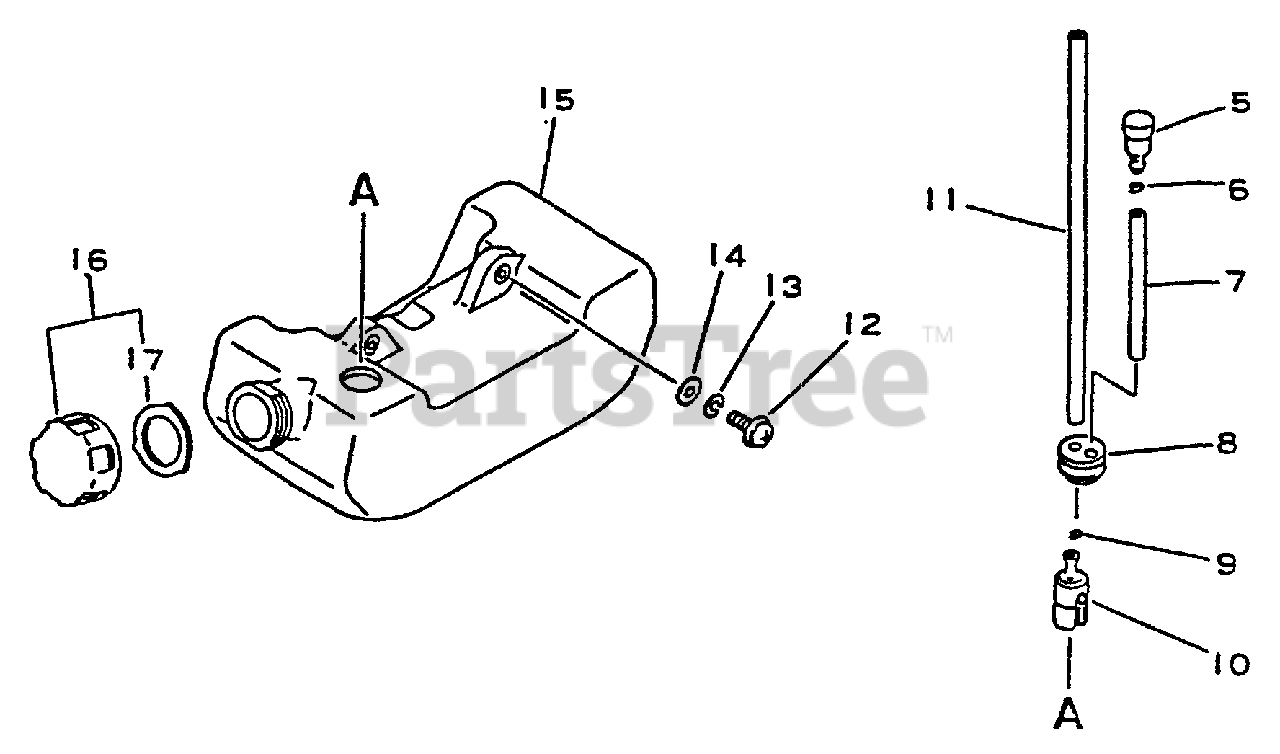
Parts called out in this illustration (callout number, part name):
5	VENT ASSY
6	RETAINER, PIPE
7	PIPE, FUEL 3x-5x-70 BLACK
8	GROMMET, FUEL
9	CLIP 6 MM
10	FILTER, FUEL
11	PIPE, FUEL 3x-5x-180
12	SCREW 5×10
13	WASHER, SPRING 5
14	WASHER 5.5×12×0.8
15	TANK, FUEL
16	CAP ASSY
17	GASKET, FUEL CAP
